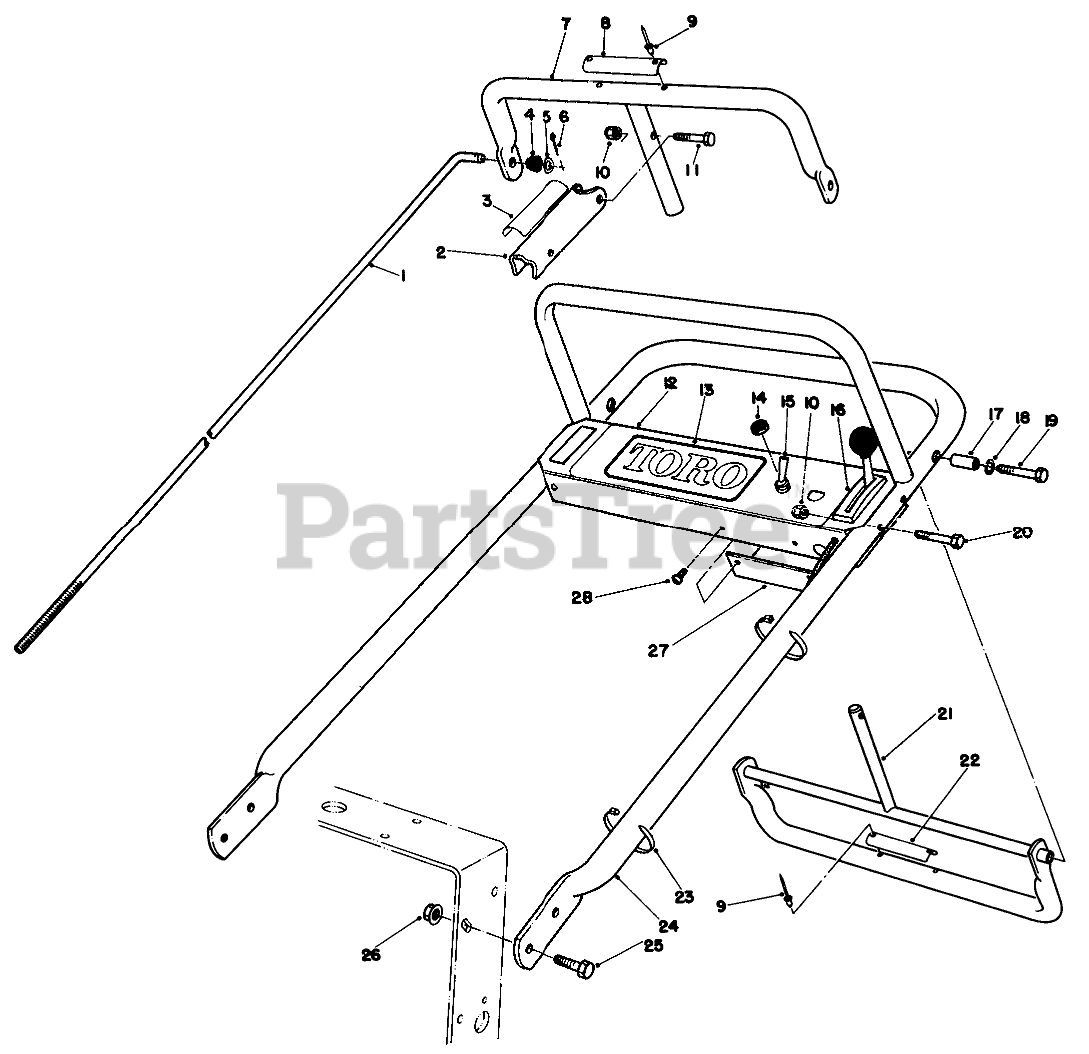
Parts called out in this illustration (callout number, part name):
1	ROD-CONTROL
2	Lever-Parking Brake
3	DECAL-LEVER, PARKING
4	GROMMET-RUBBER
5	WASHER-PLAIN
6	PIN-COTTER
7	Bar-Control
8	DECAL-CONTROL BAR
9	RIVET-BLIND
10	NUT-LOCK, NI
11	SCREW-SHH
12	Panel-Control
13	PANEL DECAL
14	NUT
15	Switch
16	THROTTLE-CONTROL
17	PIVOT-SPACER
18	WASHER-LOCK
19	SCREW-HH
20	SCREW-SHH
21	Control-Pivot
22	DECAL-REVERSE HANDLE
23	TIE-CABLE
24	HANDLE-UPPER
25	SCREW-HHF
26	NUT-HF
27	PANEL-BOTTOM
28	SCREW-HWHTF
